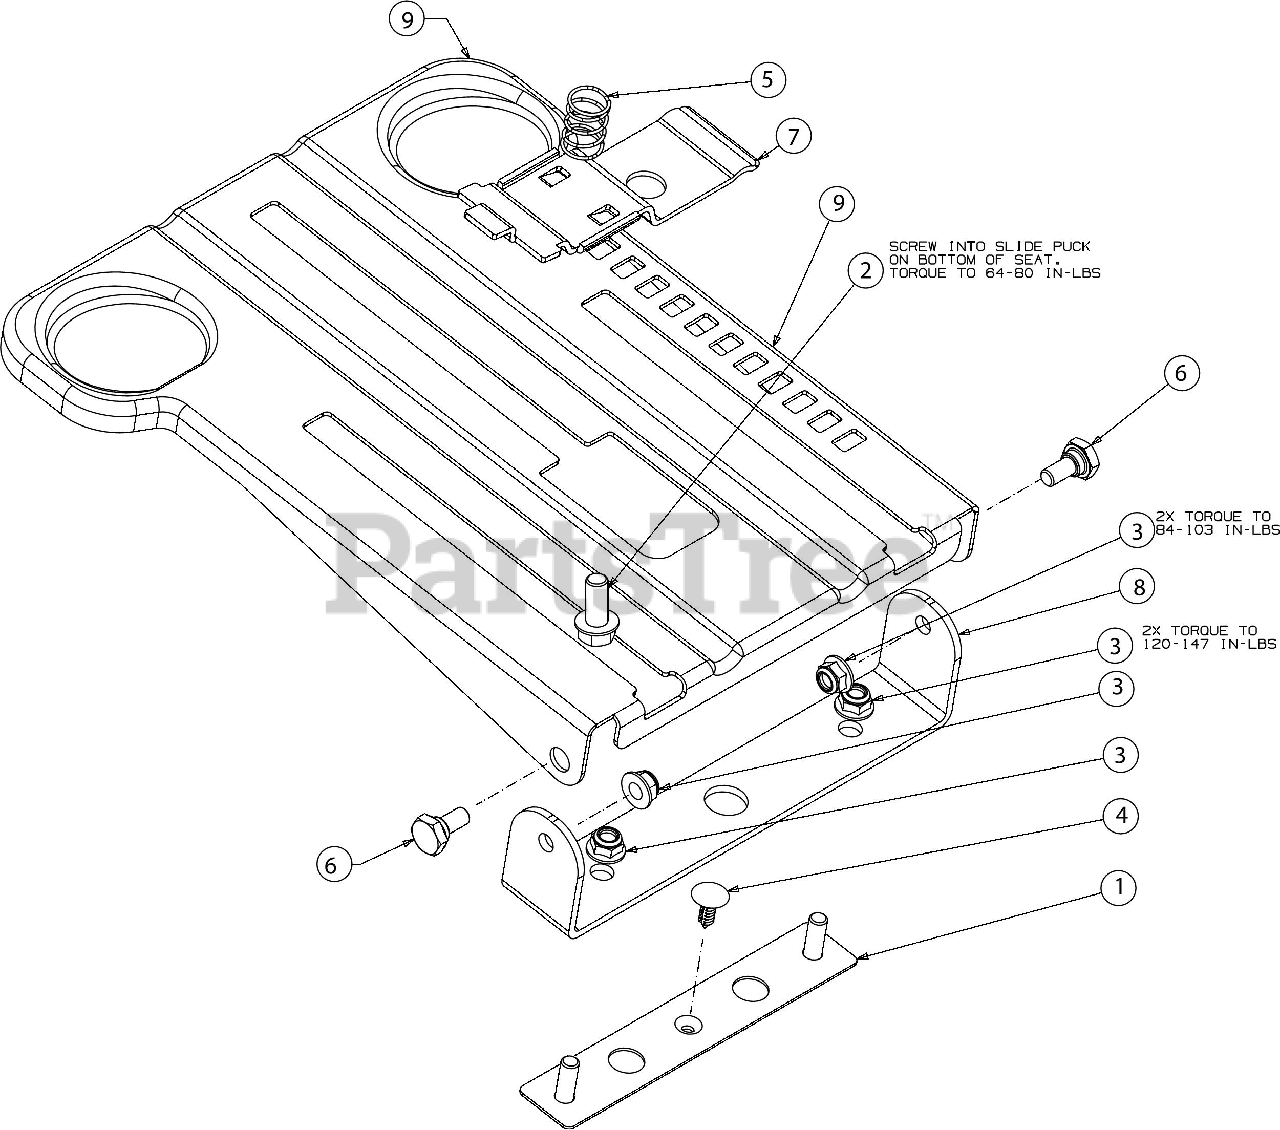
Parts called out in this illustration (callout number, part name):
1	PIVOT BRACKET PLATE
2	SCREW 3/8-16 X .875 GR5
3	FLANGE LOCK NUT 5/16-18
4	RATCHET CLIP .250
5	COMPRESSION SPRING
6	SCREW .44 X .18-5/16 X .56
7	SEAT ADJUST LEVER
8	SEAT PIVOT BRACKET
9	ANGLED MOUNTING BRACKET
